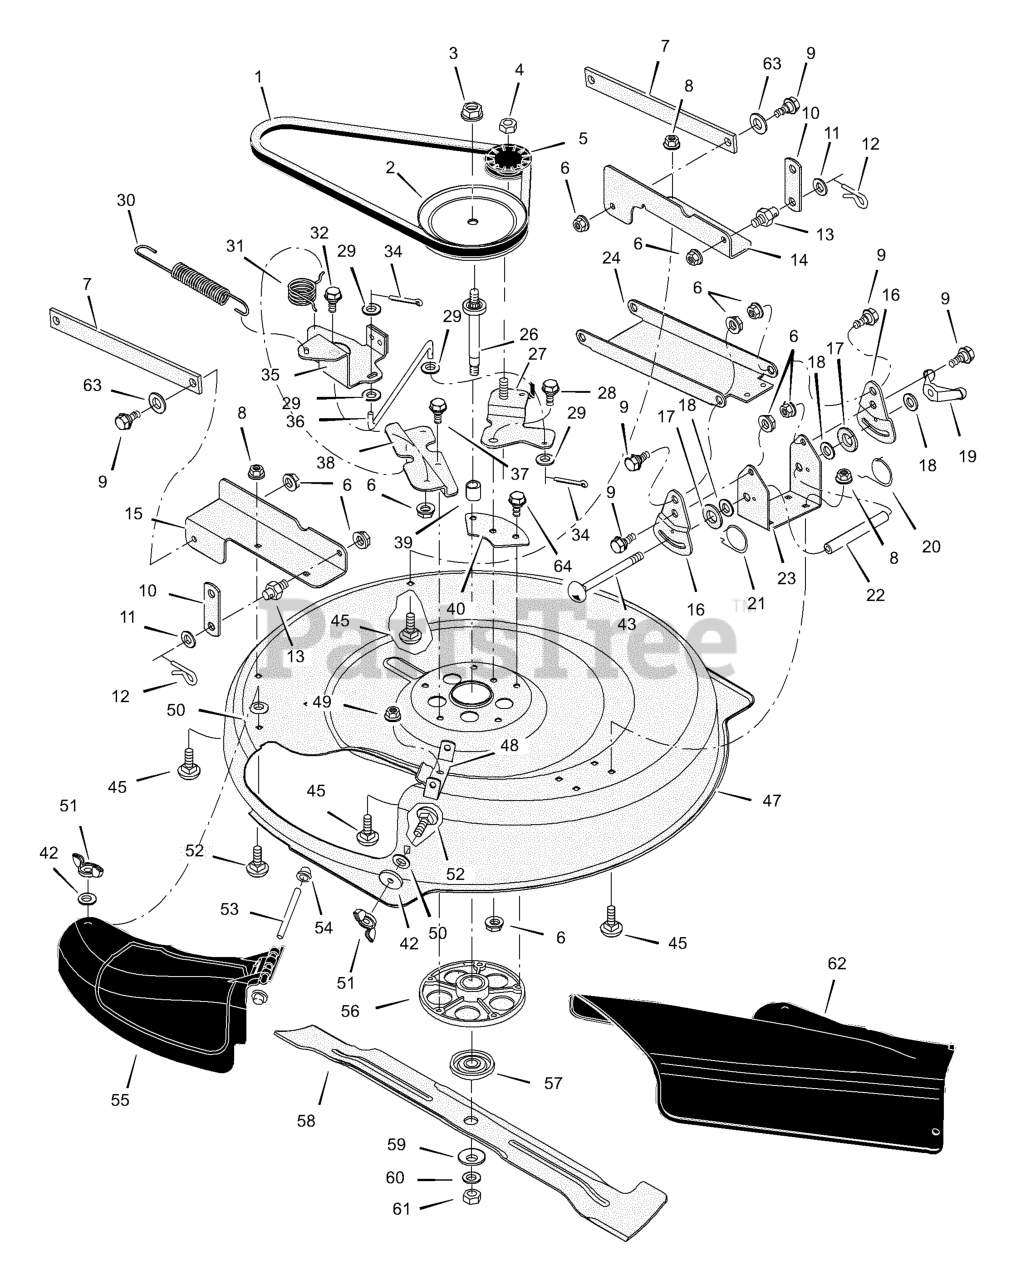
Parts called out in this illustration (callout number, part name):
1	Belt, Blade Drive
2	Pulley, Input
3	NUT, Nylock Ring, Pulley, 9/16-18
4	NUT, Hex Flange, Center Lock, 3/8-16
5	IDLER PULLEY, Fixed
6	NUT, Hex Flange, Center Lock, 3/8-16
8	NUT, Hex Flange, 5/16-18
9	BOLT, Shoulder
10	Link, Lift
11	WASHER, 1/2 x 7/8
12	PIN, Hair
13	PIN, Threaded, Shoulder, 3/8-16 x 1-7/16 Long
14	Bracket, Left Rear
15	Bracket, Right Rear
16	Plate, Adjustment
17	FRICTION PAD
18	WASHER, Flat, 1
19	WINGNUT 5/16-18
20	SPRING, Left Torsion
21	SPRING, Right Torsion
22	Tube, Spacer
23	Bracket, Deck
24	Hanger, Front
26	Shaft, Splined
27	Arm Assembly , Idler
28	BOLT, Shoulder, 3/8-16 x 1/2
29	WASHER, Flat, 5/16
30	SPRING, Extension
31	Spring, Torsion
32	BOLT, Shoulder, 3/8-16 x 3/5
34	COTTERPIN, 3/4
35	Arm Assembly, Brake
36	Link, Idler Arm
37	SCREW, Self Tap, 3/8-16 x 1-1/4
38	Bracket, Brake Mounting
39	Spacer, Jackshaft
40	Plate, Idler Mounting
43	Bolt, Carriage
45	BOLT, Carriage, 5/16-18 x 5/8
47	Housing, Blade
48	Hinge, Mulching Cover
49	NUT, Hex Flange, Center Lock, 5/16-18
50	NUT, Push, 1/4
51	NUT, Wing, 5/16-18
52	BOLT, Carriage, 5/16-18 x 3/4
53	Rod, Chute Deflector
54	CAP, Push On
55	Cover, Mulch (Black)
56	Housing, Jackshaft
57	Adapter, Deck/Blade
59	WASHER, Belleville
60	WASHER, Hardened
61	NUT, Blade, 9/16-18
62	Deflector, Chute (Black)
63	WASHER, 1/2 x 1-1/2
64	SCREW, Self Tap, 3/8-16 x 1-1/4
